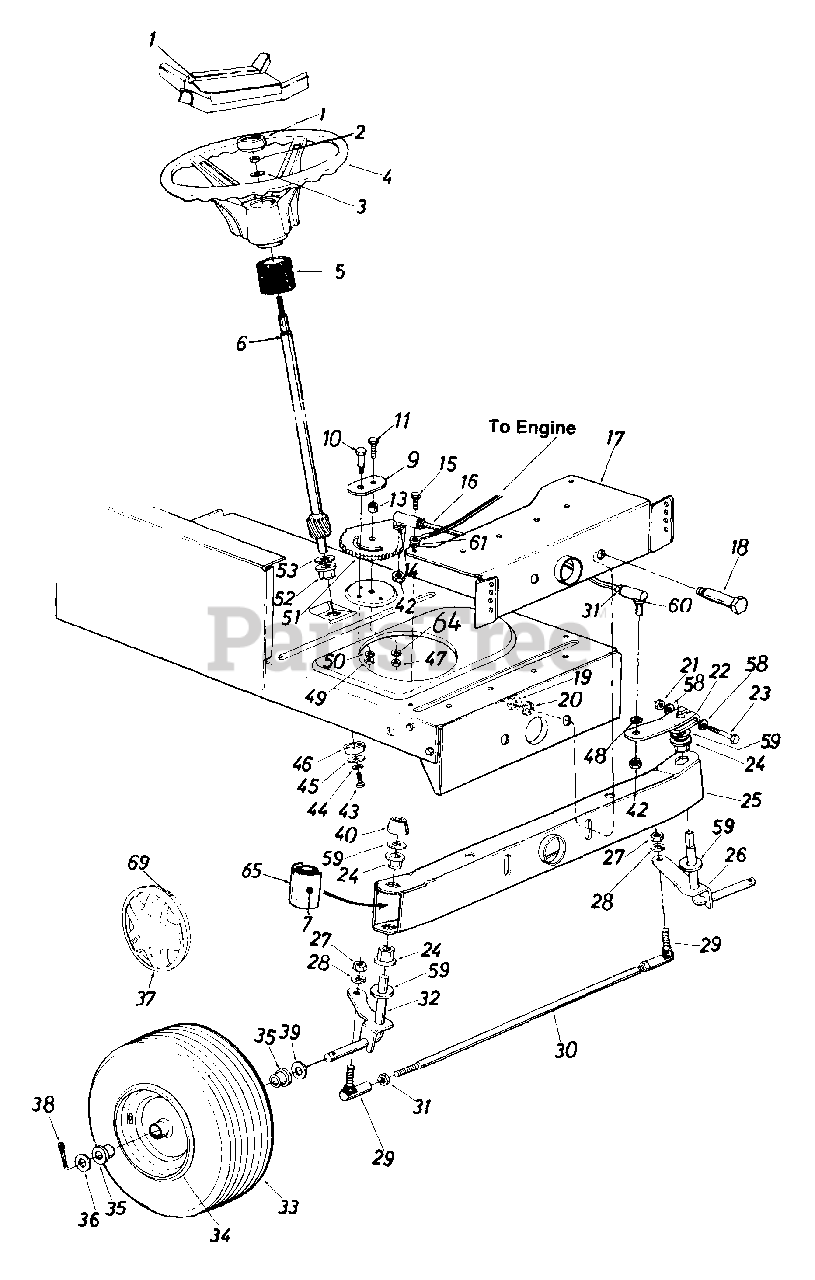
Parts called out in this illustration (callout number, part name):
1	Steering Wheel Cap
2	Hex L-Nut 5/16-24 Thd.
3	Belleville Wash..345" I.D.
4	Steering Wheel (3 Spoke)
5	Steering Bellow
6	Steering Shaft
7	Grease Fltting
9	Retainer Plate
10	Shoulder Bolt .437" Dia. x .35" Lg. 5/16-18 Thd.
11	Hex Bolt 3/8-24 x 1.0" Lg. (Grade 5)
13	Spacer .380" I.D. x .625" O.D. x .227"
14	L-Wash. 3/8" I.D.
15	Hex Wash. Hd. Self-Tap Scr.
16	Steering Drag Link
17	Front Pivot Brkt.
18	Shoulder Bolt .498" Dia. x 2.04" Lg. 3/8-16 Thd.
19	Hex Nut 3/8-16 Thd.
20	L-Wash. 3/8" I.D.
21	Hex Cent. L-Nut 5/16-24 Thd.
22	Steering Arm Front Axle
23	Hex Bolt 5/16-24 x 2.00" Lg. (Grade 5)
24	Hex Flg. Brg..632" I.D.
26	Front Axle Ass'y.- L.H,
27	Hex Nut 3/8-24 Thd.
28	L-Wash. 3/8" I.D.
29	Ball Joint 3/8-24 Thd.
30	Tie Rod
31	Hex Jam Nut 3/8-24 Thd.
32	Front Axle Ass'y.- R.H.
33	Wheel Ass'y. Comp.
34	Front Wheel Rim Only
36	Fl-Wash. .635" I.D. x 1.59" O.D.
37	Hub Cap (Gray)
38	Cotter Pin 1/8" Dia. x 1.25" Lg.
39	Fl-Wash..640" I.D. x .24" O.D.
40	Push Cap
42	Hex Jam Nut 3/8-24 Thd.
43	Hex L-Bolt 5/16-18 x .62"
44	L-Wash. 5/16" I.D.
45	Fl-Wash..33" I.D. x 1.25" O.D.
46	Spacer (Plastic)
47	Hex Cent. L-Nut 3/8-24 Thd.
48	L-Wash. 3/8" I.D.
49	Hex Cent. L-Nut 5/16-18 Thd.
50	L-Wash. 5/16" I.D.
51	Steering Gear Segment
52	Hex Flg. Brg..634 I.D.
53	Fl-Wash. (Hardened)
58	Wave Wash..32" I.D. x .62"
59	Fl-Wash. (Hardened)
60	Drag Link Sall Joint 3/8-24 Thd.
61	Ext. L-Wash. 5/16" I.D.
64	Bell-Wash..39" I.D. x 1.38" O.D.
65	Pivot Bar End Cap
69	Spring Clip
